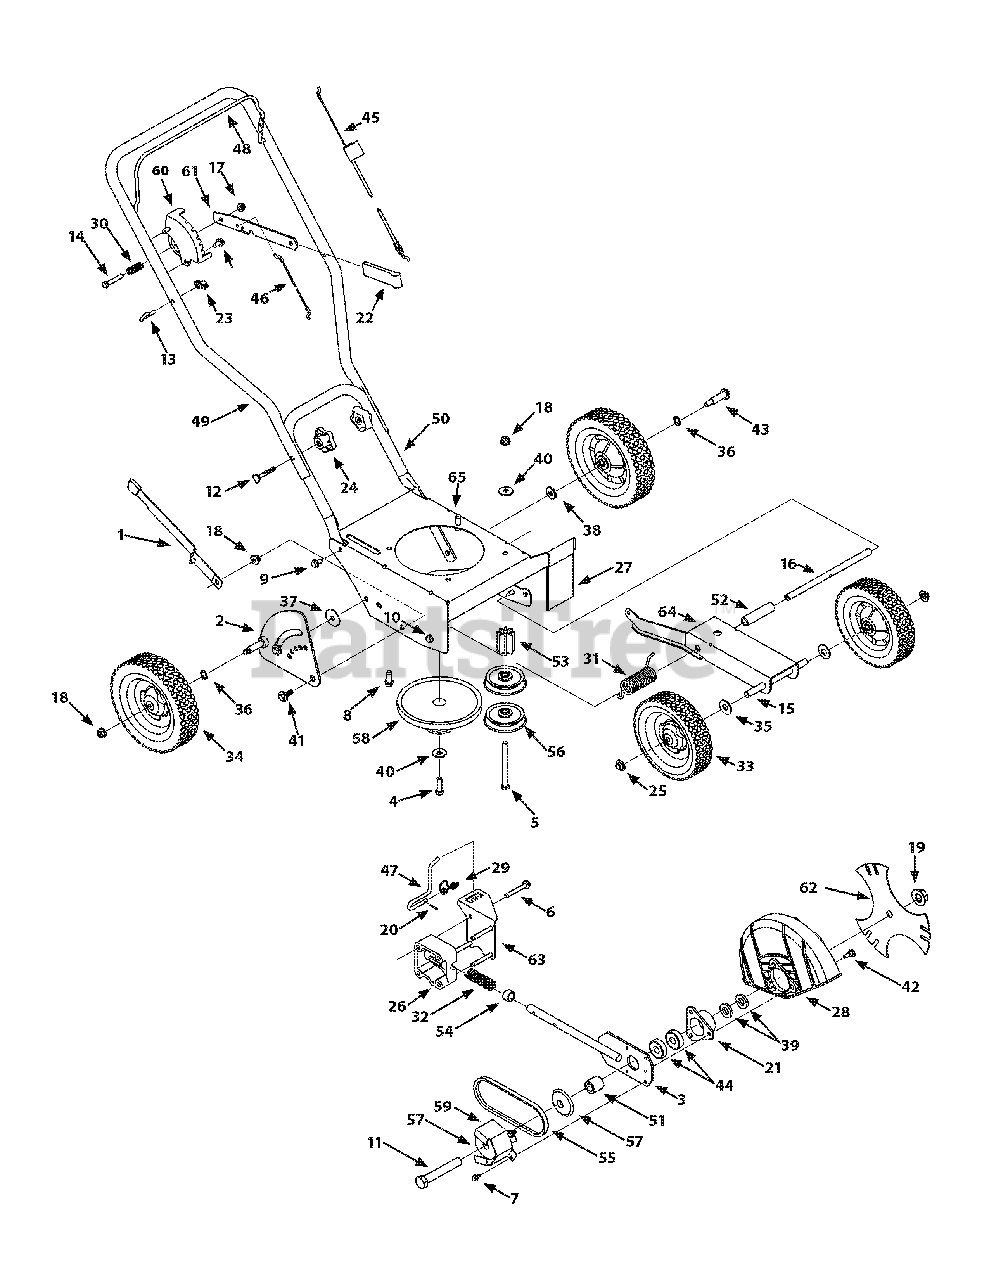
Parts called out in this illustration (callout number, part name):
1	Curb Height Adjustment Lever
2	Curb Height Adjuster Plate
3	Blade Plate Assembly
4	Screw 3.8-24
5	Screw 3.8-16
6	Hex Screw, 5.16-18
7	Self-tapping Screw, 1.4-20
8	Screw, 3.8-16
9	Hex Screw, 5.16-12
10	Hex Screw 5.16-18
11	Hex Screw, 5.8-18
12	Carriage Bolt, 5.16-18
13	Rope Guide (Eye Bolt)
14	Hex Screw, 5.16-18
15	Axle Shaft .50x6.65
16	Frame Spacer .50x9.25
17	Lock Flange Nut, 5.16-18
18	Flange Nut 3.8-16
19	Flange Nut, 5.8-18
20	Clevis Pin 3.32 x .625
21	Bearing Cup
23	Wing Nut
24	Star Knob
25	Push Cap 1.2h rod
26	Bearing Block
27	Debris Guard
28	Blade Guard
29	Double Torsion Spring
30	Compression Spring
31	Torsion Spring
32	Compression Spring
33	Wheel 7 x 1.75 T-Tread
34	Wheel 8 x 1.75 T-Tread
35	Flat Washer 1.2 x 1.25 x .10
36	Wave Washer .531 x .781 x .013
37	Flat Washer, .385 x 1.5 x .075
38	Flat Washer .385 x 1.0 x .135 õ
39	Flat Washer .635x1.24x.181
40	Bell Washer,.396 x 1.140
41	Shoulder Screw, 3.8-16
42	Shoulder Screw
43	Shoulder Screw, 3.8-16
44	Bearing, .625 ID x 1.57 OD
45	Control Cable (Briggs & Stratton)
46	Wheel Adjustment Cable
47	Blade Adjustment Rod
48	Bail Handle
49	Upper Handle
50	Lower Handle
51	Spacer, .63 x 1.12 x 1.06
52	Spacer
53	Pulley Mount Spacer
54	Spacer, .64 x.88 x .50
56	Flat Idler Pulley, 2.5 OD
57	Sheave
58	Combination Flywheel Pulley
59	Belt Guard
62	Tri-Star Blade
63	Bracket Plate
65	Frame
